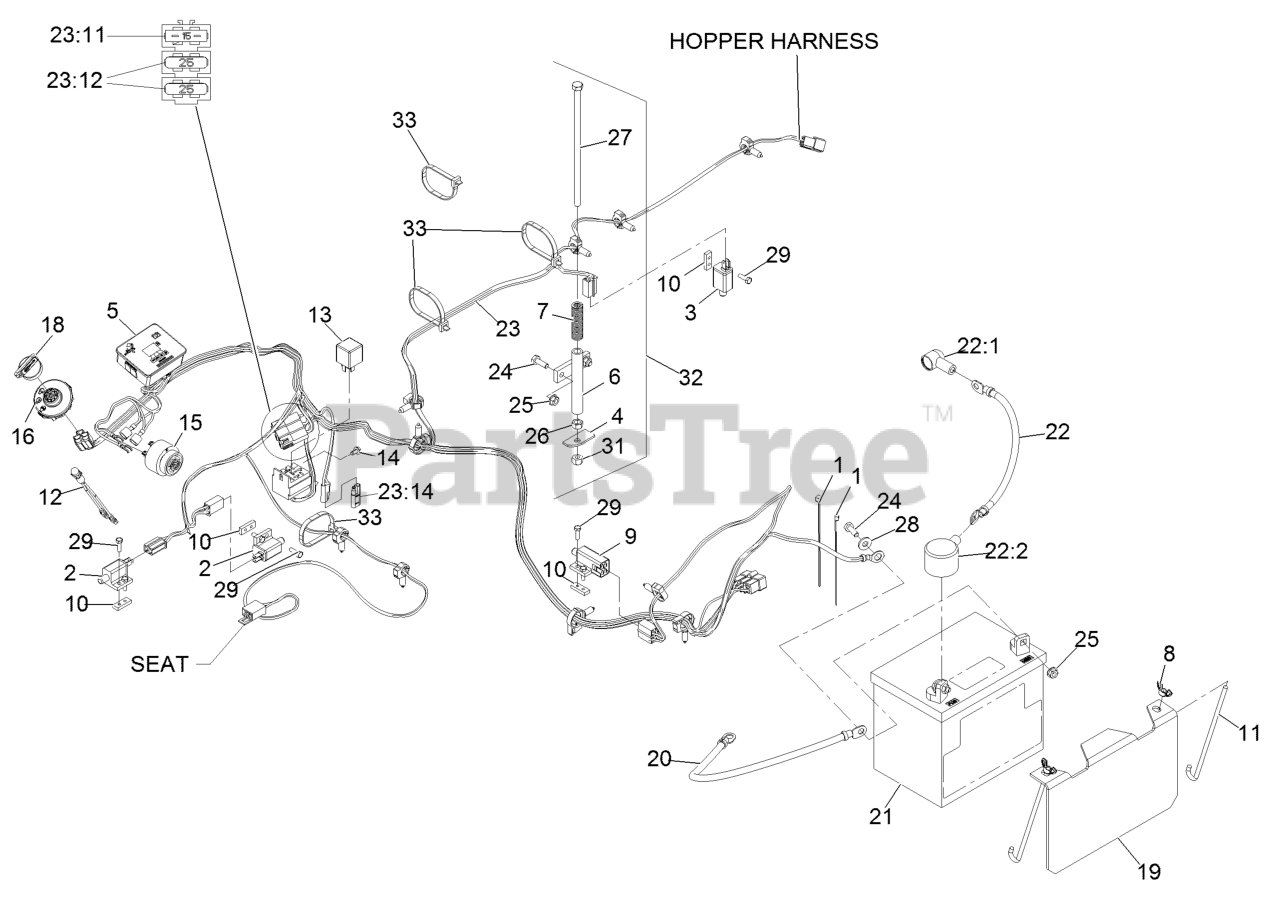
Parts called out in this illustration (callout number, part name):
1	TIE-CABLE
2	SWITCH-OPEN, NORMALLY
3	SWITCH-CLOSED, NORMALLY
4	Plate-Switch
5	HOUR METER ASM
6	MOUNT-SPRING, SEAT
7	SPRING-SWITCH, SEAT
8	WINGNUT
10	PLATE-TAPPED
11	BOLT-HOLDDOWN
12	INDICATOR-LED, RED
14	SCREW-HWH
15	ALARM-TONE, DUAL
18	KEY-IGNITION
19	HOLD DOWN-BATTERY
20	CABLE-BATTERY, NEGATIVE
21	Battery (300 Cca, Wet)
22	CABLE-BATTERY, POSITIVE
22:1	INSULATOR-SOLENOID
22:2	INSULATOR-BATTERY
23	HARNESS-WIRING
23:11	FUSE-BLADE, 15 AMP
23:12	FUSE-BLADE, 25 AMP
23:14	CAP-PLUG
24	SCREW-HH
26	NUT-HEX
27	SCREW-HH
28	WASHER-FLAT
31	NUT-LOCK, NI
32	HOPPER SWITCH ACTUATOR AS
33	TIE-PLASTIC
